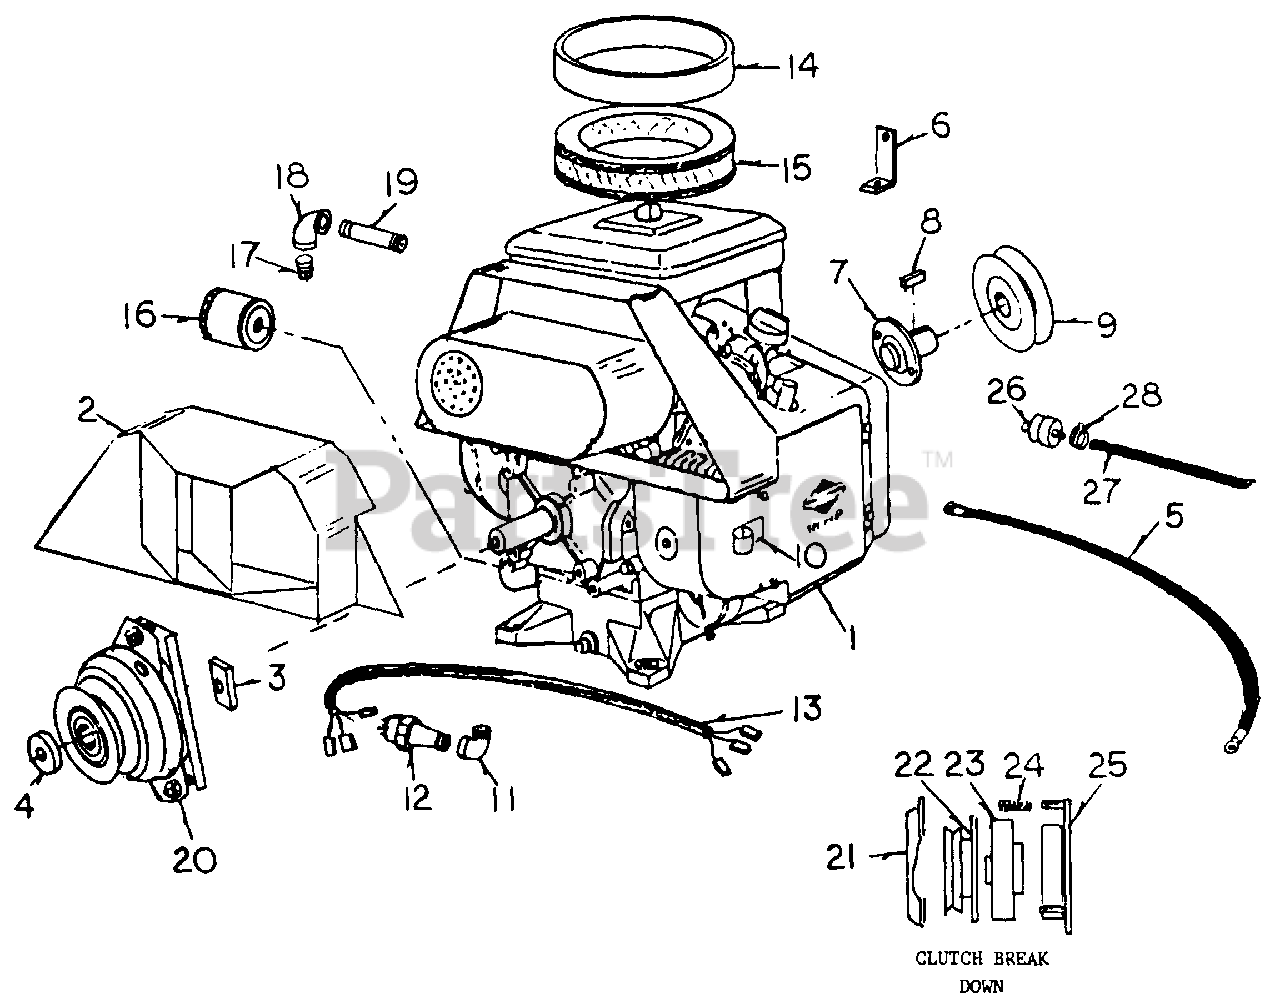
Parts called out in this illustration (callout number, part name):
1	Briggs & Stratton Twin 18 HP
4	Clutch Retainer Washer
6	Wire Standoff
8	Key Stock, 1/4"
10	Starter Cable Retainer
11	Street Elbow, 1/8"
12	Oil Sending Unit
13	Wire Harness
14	Pre Cleaner
15	Air Cleaner Cartridge
16	Oil Filter
18	Elbow, 3/8"
19	Nipple, 3/8"
20	Clutch
22	Clutch Armature
23	Clutch Rotor
24	Spring & Nut Set
25	Clutch Coil
26	Fuel Filter
28	Fuel Line Clamp
